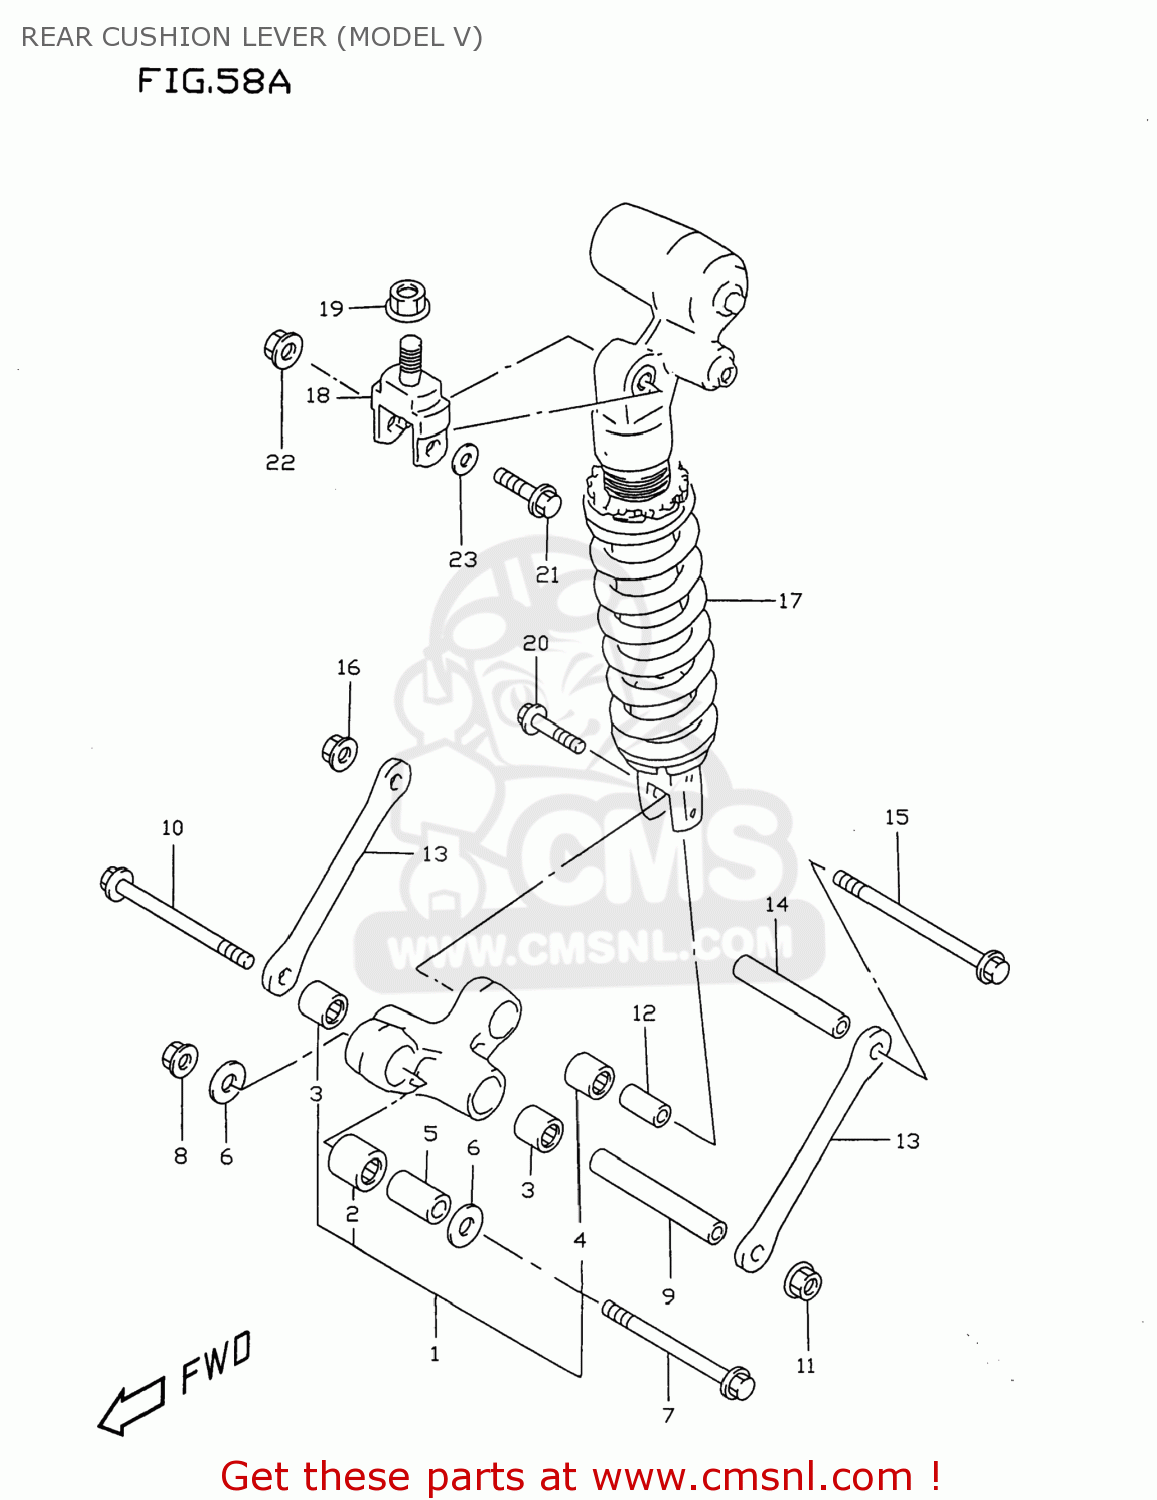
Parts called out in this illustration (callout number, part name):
1	LEVER SET,RR CUSHION
2	BEARING(20X27X30)
3	BEARING(17X24X20)
4	BEARING(17X24X26)
5	SPACER,RR CUSHION LEVER FR
6	WASHER
7	BOLT,RR CUSHION LEVER FR
8	NUT 12MM
9	SPACER,RR CUSHION LEVER CTR
10	BOLT,RR CUSHION LEVER CTR
11	NUT 12MM
12	SPACER,RR CUSHION LEVER
13	ROD,RR CUSHION LEVER
14	SPACER,RR CUSHION LEVER CTR
15	BOLT,RR CUSHION LEVER CTR
16	NUT 12MM
17	ABSORBER ASSY,RR SHOCK
18	BRACKET,RR SHOCK ABSORBER UP
19	NUT
20	BOLT(10X44)
21	BOLT
22	NUT
23	WASHER (10X20X2.3)
